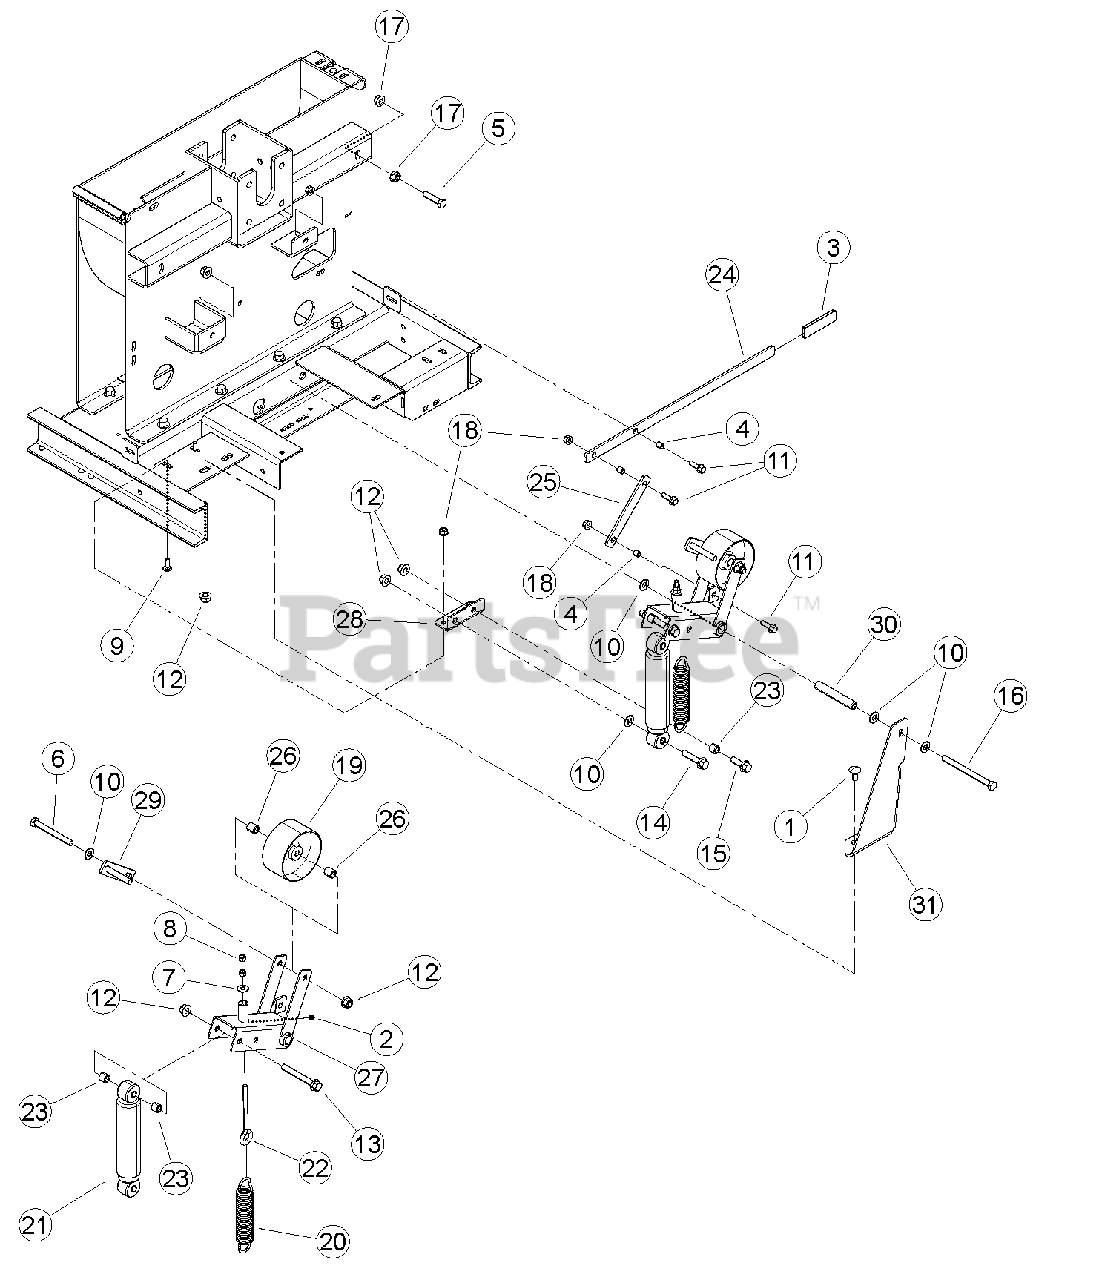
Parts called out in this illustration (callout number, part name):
1	BOLT, 1/2 X 1 GR5 CRG ZP
2	FITTING, 1/4 SELF-TAP GREASE
3	GRIP, CLUTCH HANDLE
4	BUSHING, 3/8 X 1/2 SLEEVE LUBE
5	BOLT, 1/2 X 2 GR5 HEX CAPSCREW ZP
6	BOLT, 1/2 X 4-1/2" GR5 HHCS NC ZP
7	WASHER, 3/8" FLAT ZP
8	NUT, 3/8" HEX NC ZP
9	BOLT, 3/8 X 1" GR5 CRG NC ZP
10	WASHER, 1/2" SAE FLAT ZP
11	BOLT, 3/8 X 1-1/4 FLANGE NC
12	NUT, 1/2-13 NYLOCK FLANGE
13	BOLT, 1/2-13 X 4 HWH GR5 CZP
14	BOLT, 1/2 -13 X 2-1/4 FLANGE NC
15	BOLT, 1/2-13 X 1-1/2 GR5 FLANGE NC
16	BOLT, 1/2 X 6 G5 HCS - ZP
17	NUT, 1/2 SPIRAL LOCK NC ZP
18	NUT, 3/8-16 NYLOCK FLANGE
19	PULLEY, IDLER 5" X 2.50"
20	SPRING, 7-3/4" EXTENSION
21	ABSORBER, IDLER SHOCK
22	EYEBOLT, 3/8 X 5" LG 4-1/4 THD ZP
23	SPACER, 0.75 X 0.620
24	LEVER, CLUTCH ENGAGEMENT
25	LINK, ENGAGEMENT ARM
26	SPACER, IDLER SHEAVE
27	WELDMENT, IDLER ARM
28	BRACKET, SPRING ANCHOR
29	WELDMENT, BELT PIN
30	BUSHING, IDLER PIVOT
31	BRACE, IDLER
